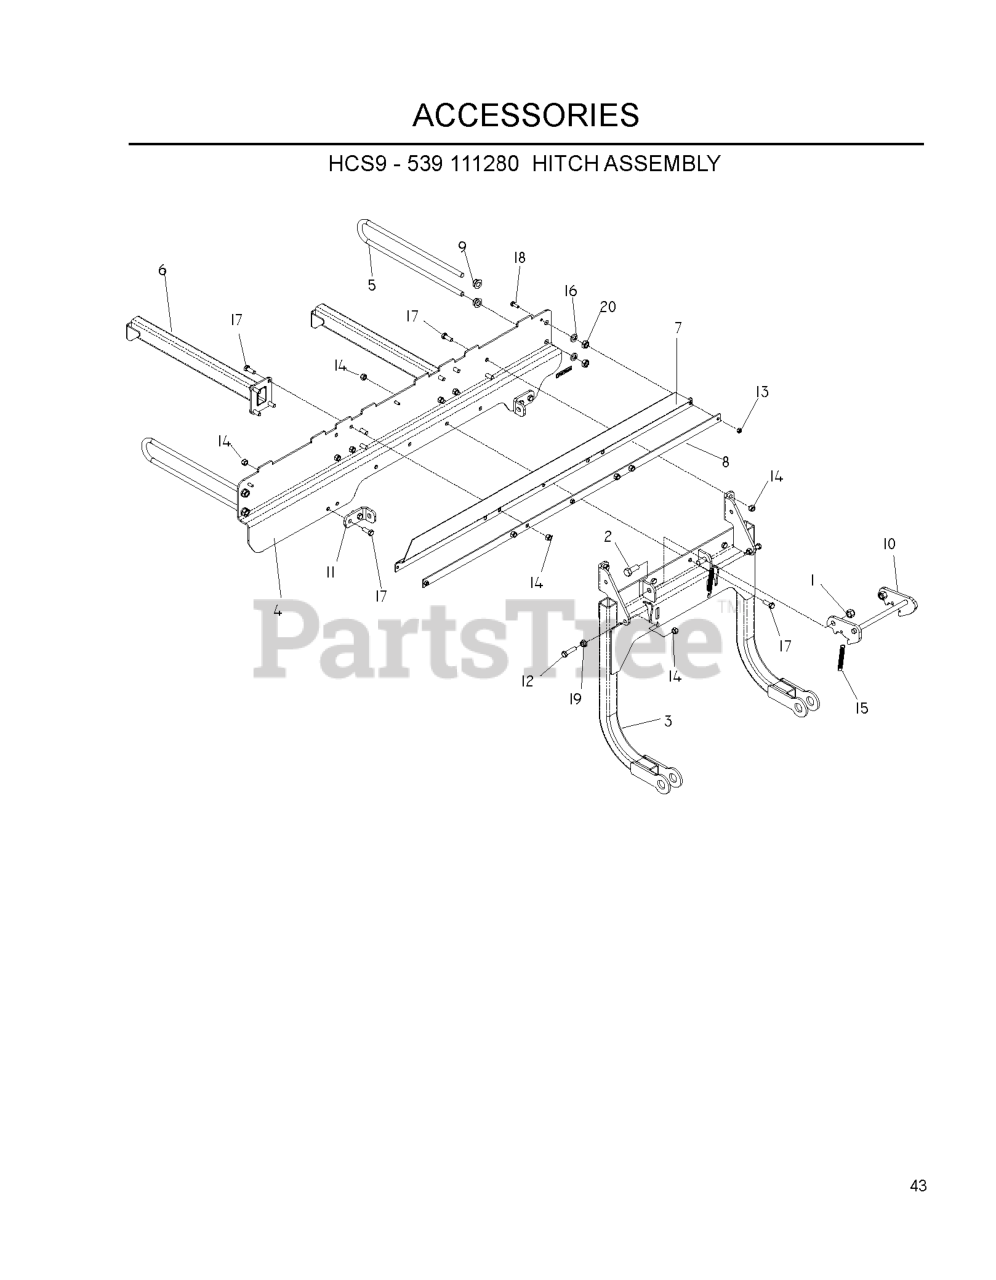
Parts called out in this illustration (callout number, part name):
1	NUT 1/2-13 HEX NYLOC ZD
2	HCS 1/2-13 X 1-1/4
3	HITCH WELDMENT
4	MOUNT Z BRACE
5	SUPPORT, OUTER
6	SUPPORT ARM WELDMENT
7	SEAL, RUBBER
8	SEAL STRAP
9	NUT 1/2-13 HEX
10	LATCH WELDMENT
11	BRACKET, SUPPORT
12	HCS 3/8C X 1 1/2
13	NUT.1/4-20.HEX.NYLOC.ZD
14	NUT 3/8-16 NYLOC
16	WASHER 1/2" SPLIT LOCK
17	HCS 3/8-16X1.GRD.5.ZD
18	HCS 1/4C X 3/4 HCS
19	NUT 3/8C WHIZ
20	NUT 1/2 HEX JAM
